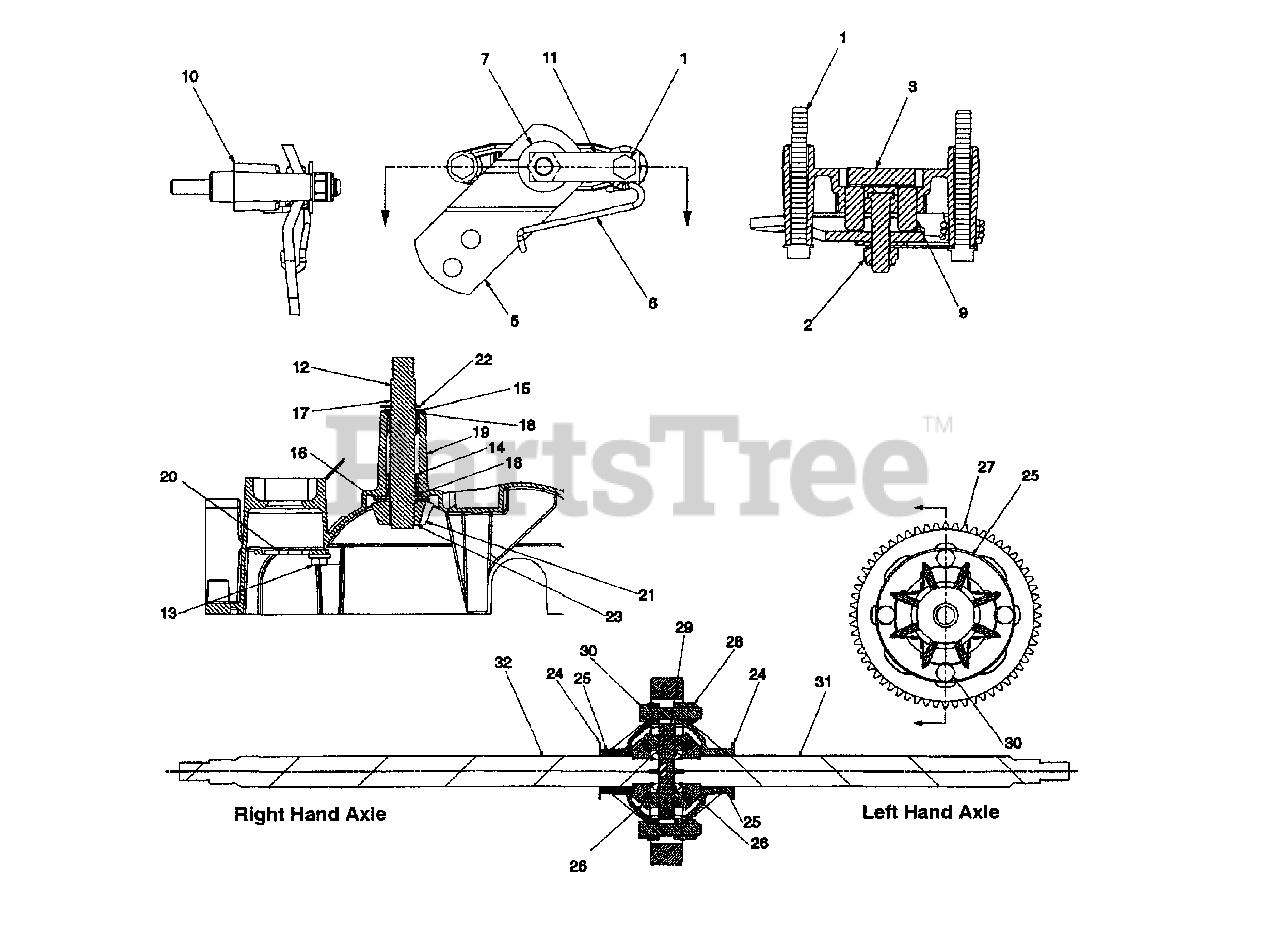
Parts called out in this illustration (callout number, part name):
1	Hex Wash. Hd. Scr. 1/4-20 x 2.37
2	Nylon L-Nut 5/16-24 Thd.
3	Brake Puck
5	Brake Arm
6	Torsion Spring
7	Fl-Wash. .343" I.D. x .88" O.D.
9	Brake Pin
10	Brake Yoke
11	Brake Anti Rotation Brkt.
12	Input Shaft
13	Hex Washer AB-Tap Scr. 1/4-14 x 1"
14	Needle Brg. .625" I.D.
15	Fl-Wash. 5/8" I.D. x 1" O.D.
16	Thrust Wash. .635" I.D. x 1.25" O.D
17	Wire Ring
19	Upper Housing
20	Lockout Plate
21	Bevel Gear
22	Retainer Ring
23	Retainer Ring
24	Fl-Wash. 1" I.D. x 1.8" O.D.
25	Differential Housing
26	10T Miter Gear
27	Spur Gear 60T
28	Hex L-Nut 3/8-24 Thd.
29	Cross Shaft
30	Hex Bolt 3/8-24 x 2"
31	Axle Assembly L.H.
32	Axle Assembly R.H.
